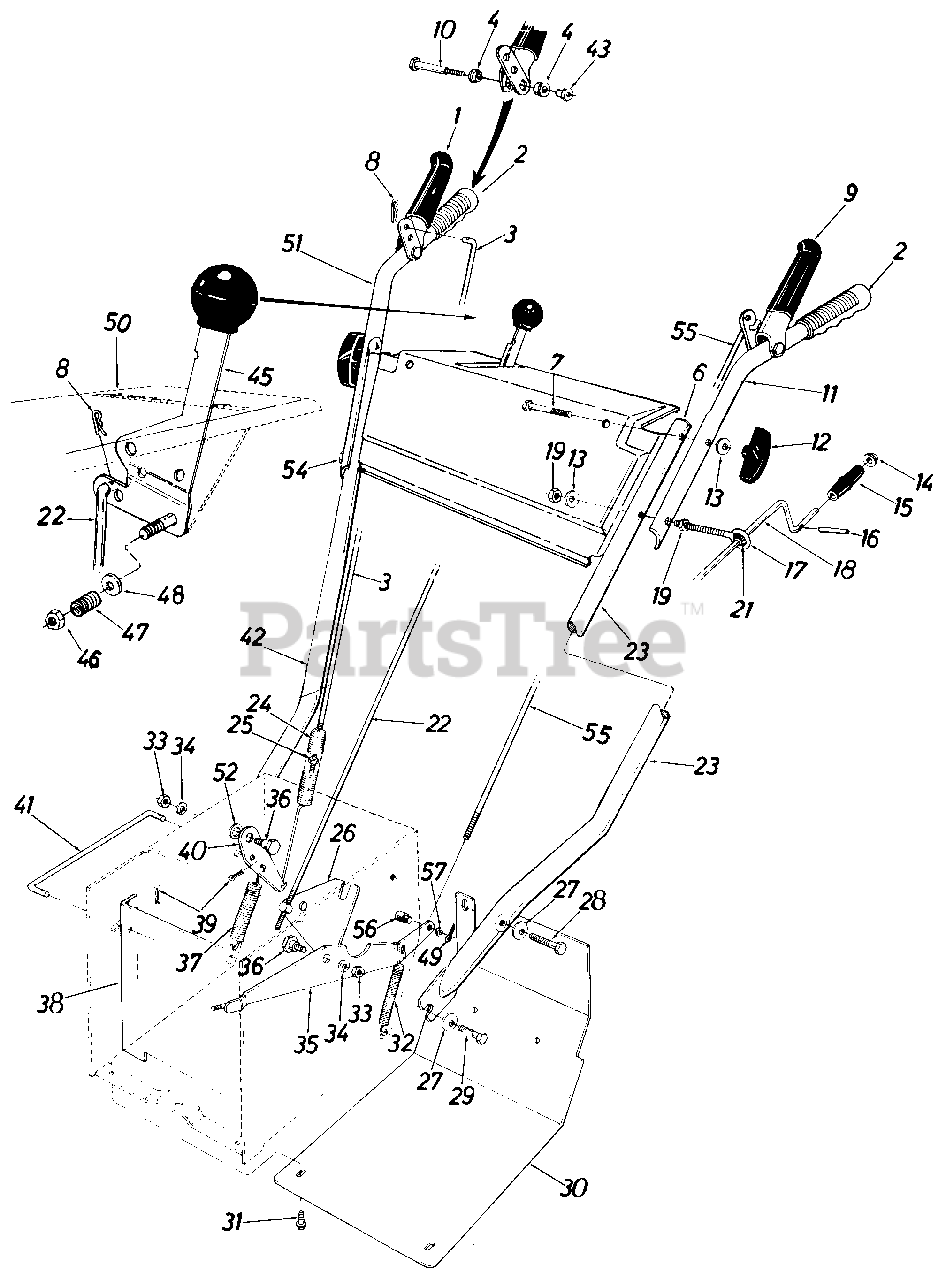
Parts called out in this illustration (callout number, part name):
1	Clutch Grip Ass'y. R.H.
2	Hand Grips
3	Lockout Cable 30.5" Lg.
4	Hex Flange Brg. Plastic .38" I.D.
6	Plastic Plug
7	Hex Bolt 5/16-18 x 2.0" Lg.
8	Internal Cotter Pin
9	Clutch Grip Ass'y. L.H.
10	Shld. Bolt .374" Dia. x 1.53" Lg.
11	Upper Handle Half L.H.
12	Hand Knob
13	Belleville Wash. 5/16" I.D.
14	Push Nut 3/8" Rod
15	Knob 3/8" I.D.
16	Roll Pin .12 Dia. x .63" Lg.
17	Eyebolt
18	Chute Crank Ass'y.
19	Hex Nut 5/16-18 Thd.
21	Chute Crank Grommet
22	Shifting Rod
23	Lower Handle Half L.H.
24	Extension Spring .75" O.D. x 5.0" Lg.
25	Hex Ins. L-Nut 1/4-20 Thd.
26	Shifting Linkage Bracket
27	Belleville Wash. .40 I.D. x .88 O.D. x .060
28	Hex Bolt 3/8-16 x 2.0" Lg.
29	Hex Wash. Hd. Self-Tap Scr. 3/8-16 x .75" Lg.
30	Frame Cover
31	Hex Wash. Hd. Self-Tap Scr. 1/4-20 x .50" Lg.
32	Extension Spring .38" O.D. x 3.25" Lg.
33	Hex Jam Nut 3/8-16 Thd.
34	L-Wash. 3/8" I.D.
35	Auger Clutch Brkt. Ass'y.
36	Shld. Bolt .625" Dia. x .170" Lg. (3/8-16)
37	Extension Spring .38" O.D. x 3.25" Lg.
38	Drive Pulley Support Brkt. Ass'y.
39	Cotter Pin 3/32" Dia. x .75" Lg.
40	Drive Clutch Brkt.
41	Drive Clutch Rod
42	Lower Handle Half R.H.
43	Shld. Nut 1/4-20 Thd.
45	Shift Handle Ass'y.
46	Hex Ins. Jam L-Nut 3/8-24 Thd.
47	Compression Spring .38" O.D. x .88" Lg.
48	Bell-Wash. .40 I.D. x .88 O.D. x .060
49	Cotter Pin 3/32" Dia. x .75" Lg.
50	Handle Panel Ass'y.
51	Upper Handle Half R.H.
52	Bell-Wash. .38 I.D. x 1.12" O.D. x .02
54	Carriage Bolt 5/16-18 x 2.50" Lg.
55	Lockout Cable 36" Lg.
56	Adjustment Ferrule
57	Fl-Wash. .33" I.D. x .63" O.D.
